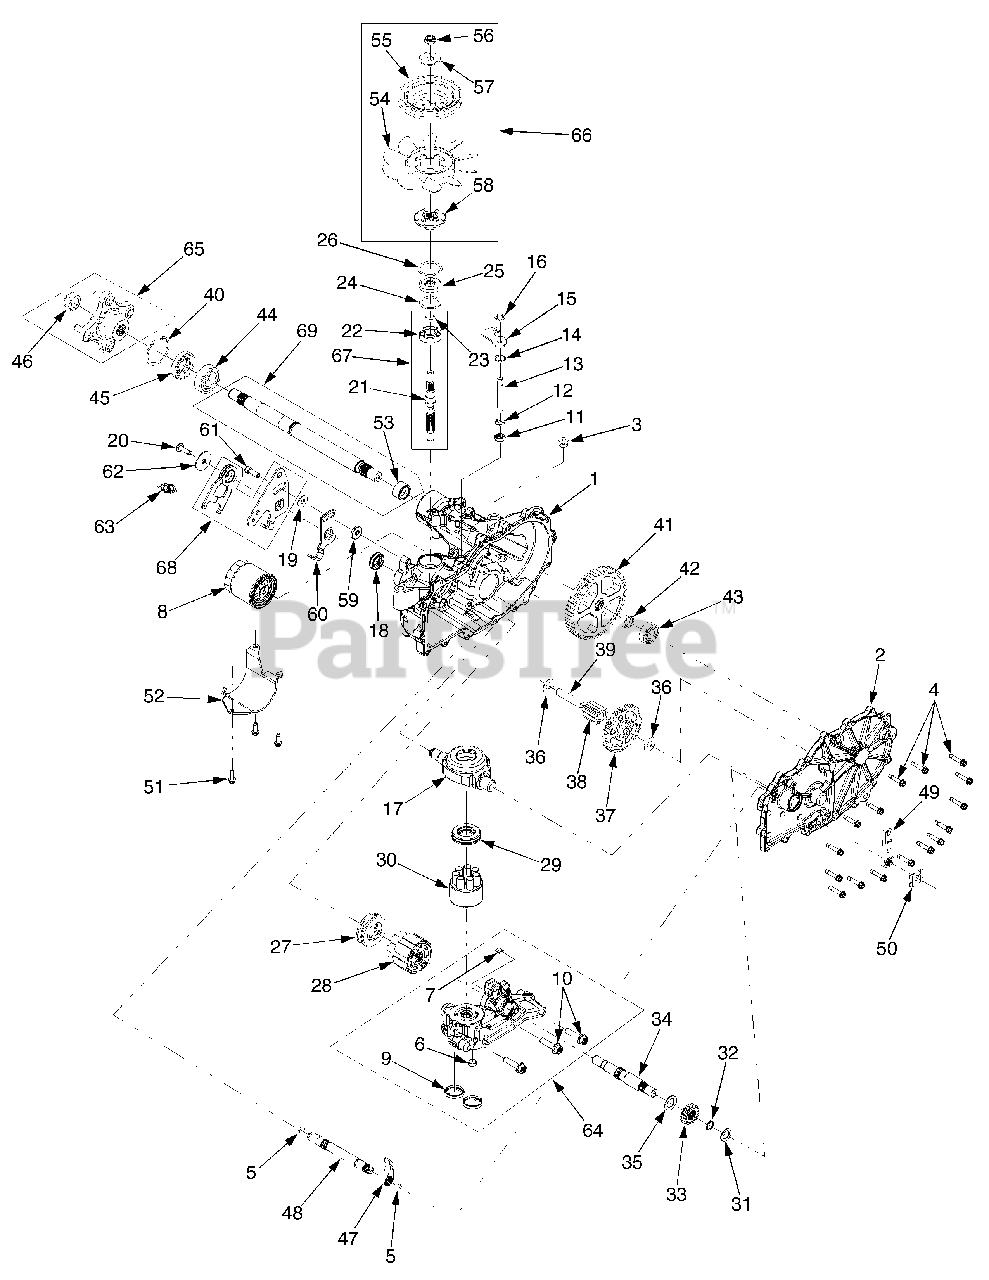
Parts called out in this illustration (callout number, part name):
1	Housing Assembly, Main RH
2	Side Cover Assembly, RH
4	Screw, Hex Self Tapping, 1/4-20 x 1.25
6	Plug, Rubber
7	Plate, Bypass
8	Filter, Oil
9	Seal. Plug, 1.25 x .25
10	Screw, 3/8-16 x 1.5 Patched
11	Seal, Lip, .375 x .75 x .25
12	Ring, Retaining, .375 Ext.
13	Rod, Bypass
14	Ring, Retaining, .75 Int.
15	Arm, Bypass
16	Ring, Retaining, .375 Push ...
17	Swashplate, Trunnion
18	Seal, Lip, 18 x 32 x 7
19	Washer, Flat, 11/32 x 7/8 x 1/16
20	Screw, 5/16-24 x 1.0
21	Shaft, Input
22	Bearing, Ball, 17mm x 40 x 12
23	Ring, Wire Retaining, .561
25	Seal, Lip, 17 x 40 x 7
26	Ring, Retaining
27	Bearing, Thrust
28	Cylinder Block - Motor
29	Bearing, Thrust Ball
30	Block, Cylinder
31	Washer, Flat, 5/8 x 1.0 x .05
32	Ring, Retaining
33	Gear, 16T
34	Shaft, Motor
35	Washer, .71 x 1.16 x .04
36	Washer, HT, .5 x 1.0 x .032 ..
37	Gear, 43T
38	Gear, 11T
39	Pin, Jackshaft
40	Ring, Retaining, 2.06 Int.
41	Gear, 54T
42	Spacer, .75 x 1.0 x .257
43	Bearing, Ball, .75 x 40 x 12
44	Bearing, Ball, 1.0 x 52 x 15
45	Seal, Lip, 25 x 52 x 10
46	Nut, Hex Lock, 3/4-16
47	Pawl, Brake
48	Shaft, Inboard Brake
49	Handle, Brake
50	Clip, Retaining
51	Screw, Hex Cap, 1/4-20 x .75
52	Guard, Filter, RH
53	Spacer, .91 x 1.02 x .625
54	Fan, 7" 10 Blade
55	Pulley, 4.5
56	Nut, Hex Insert Lock, 1/2-20
57	Washer, OD Slotted
58	Hub
59	Spacer, .32 x 1.005 x .179
60	Arm, Neutral RH
61	Screw, Hx Patch, 5/16-24 x 1.0
62	Washer, .34 x1.5 x .062
63	Spring, Extension
64	Kit, Center Section RH
66	Kit, Fan-Pulley
67	Kit, Input Shaft
68	Kit, Return Assembly
69	Kit, Axle Shaft
